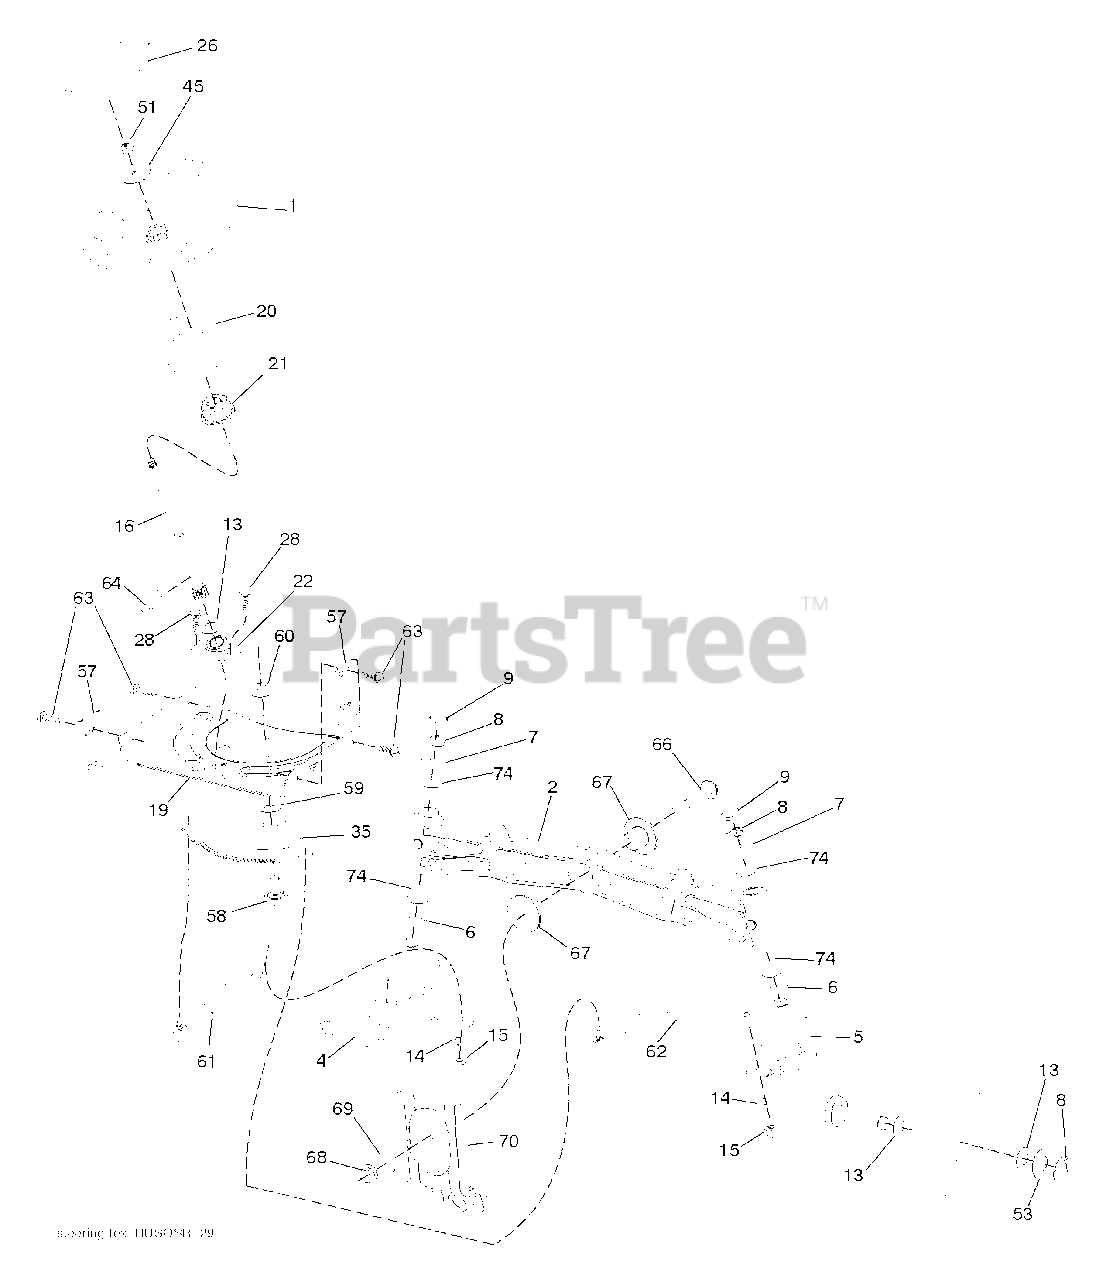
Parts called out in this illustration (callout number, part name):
1	WHEEL.STEERING.STDSRR.BLK/OV
2	AXLE HALF ASM-WELDED
4	SPINDLE.WELDED.LH.15"TEX
5	SPINDLE.WELDED.RH.15"T
8	RING CLIP
9	CAP.SPINDLE
14	WASHER, LOCK 3/8
15	NUT CROWNLOCK 3/8-24
16	SHAFT.STEER.STEALTH.DD
19	PLATE.STEER.DDL.NLT/NG
21	ADAPTER, WHEEL STNG..
22	STEERING.SUPT.LOWER.
26	CAP.WHL.STRNG.STDSRRD.SRS.BLK
28	SCREW, 3/8-16X3/4
35	GEAR.SECTOR.PLATE.DDL.
45	WASHER 9/16"ID, 2 3/8"OD
51	NUT.HEX.1/2-20
53	WASHER.HARDENED
57	BRACKET.UPSTOP.TEX
58	BOLT.SHOULDER.SECTOR.P
59	WASHER.THURST.SECTOR.S
60	NUT FLANGE LOCK 5/8-11
61	DRAGLINK.LH.BALLSTUD.D
62	DRAGLINK.RH.BALLSTUD.D
63	SCREW
64	RETAINER.CLIP.SPRING.S
66	BOLT HEX FGHD 7/16-14 X 3 SERR
67	BUSHING.PM.FRONT AXLE
68	NUT.LOCK.FLANGE.7/16
69	WASHER.1.5X.505X.118
70	BRKT.DECK.SUSPENSION.F
74	BRNG T
